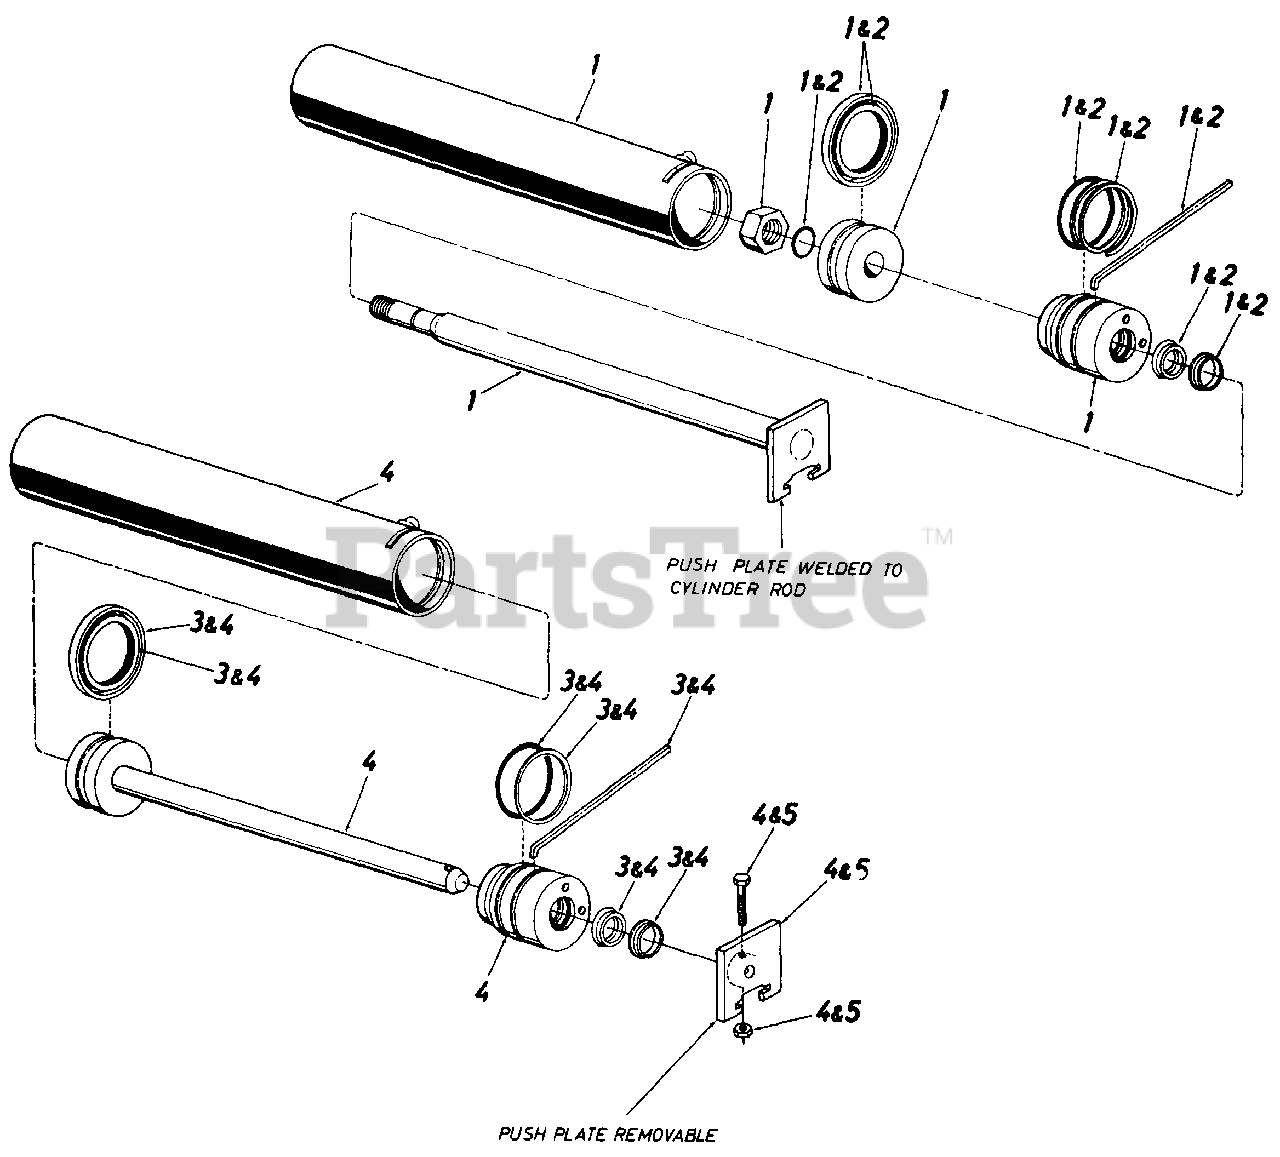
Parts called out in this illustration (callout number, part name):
1	Cylinder Ass'y. Comp.
2	4" Cyl. Kit "O"-Ring Set
3	4" Cyl. Kit "O"-Ring Set
4	Cylinder Ass'y. Comp.
5	4" Cyl. Push Plate Kit
